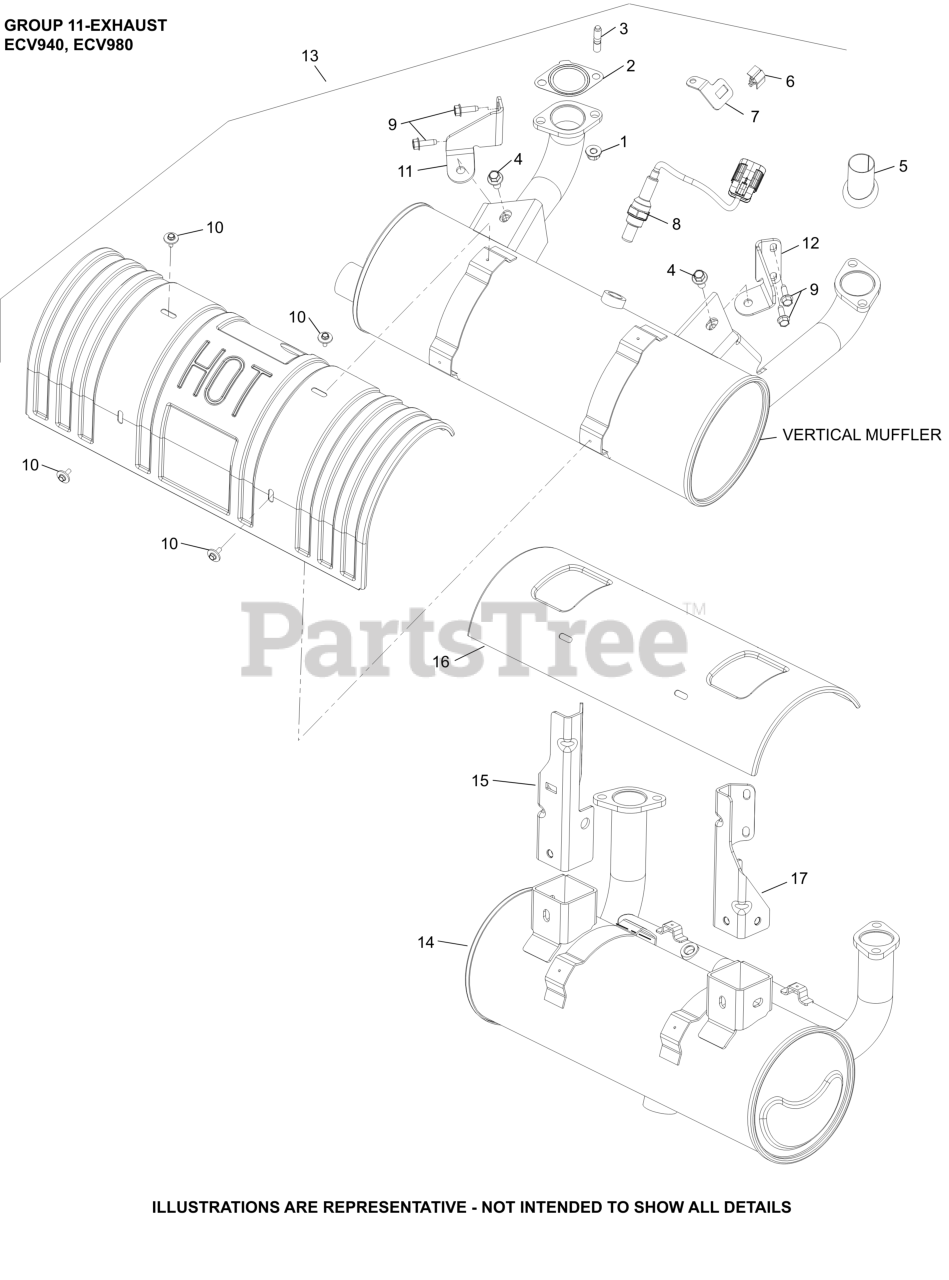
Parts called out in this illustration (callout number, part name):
1	NUT, HEX FLANGE LOCK (M8)
2	GASKET, EXHAUST
3	STUD, METRIC EXHAUST
5	LINER, EXHAUST PORT
6	CLIP, O2 SENSOR
7	BRACKET, OXYGEN SENSOR
8	SENSOR, OXYGEN (M18 x 1.5 THREADS)
